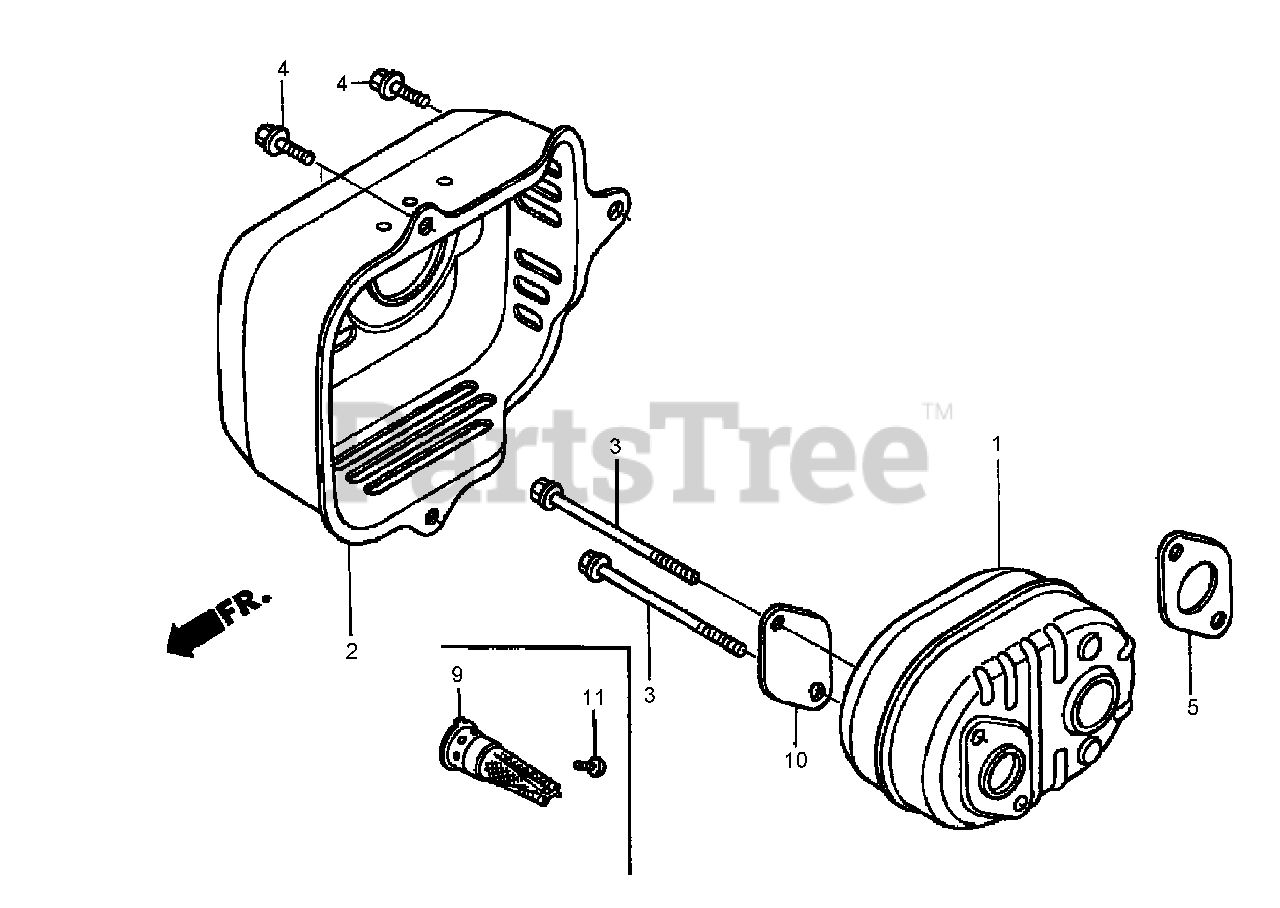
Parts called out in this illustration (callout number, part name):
1	MUFFLER
2	PROTECTOR-MUFFLER (CBU)
3	BOLT-FLANGE (6X79) (CT200)
4	BOLT-FLANGE (6X12) (CT200)
5	GASKET-MUFFLER
9	ARRESTER-SPARK
10	PLATE-NUMBER, ARRESTER
11	SCREW-TAPPING (4X6)
